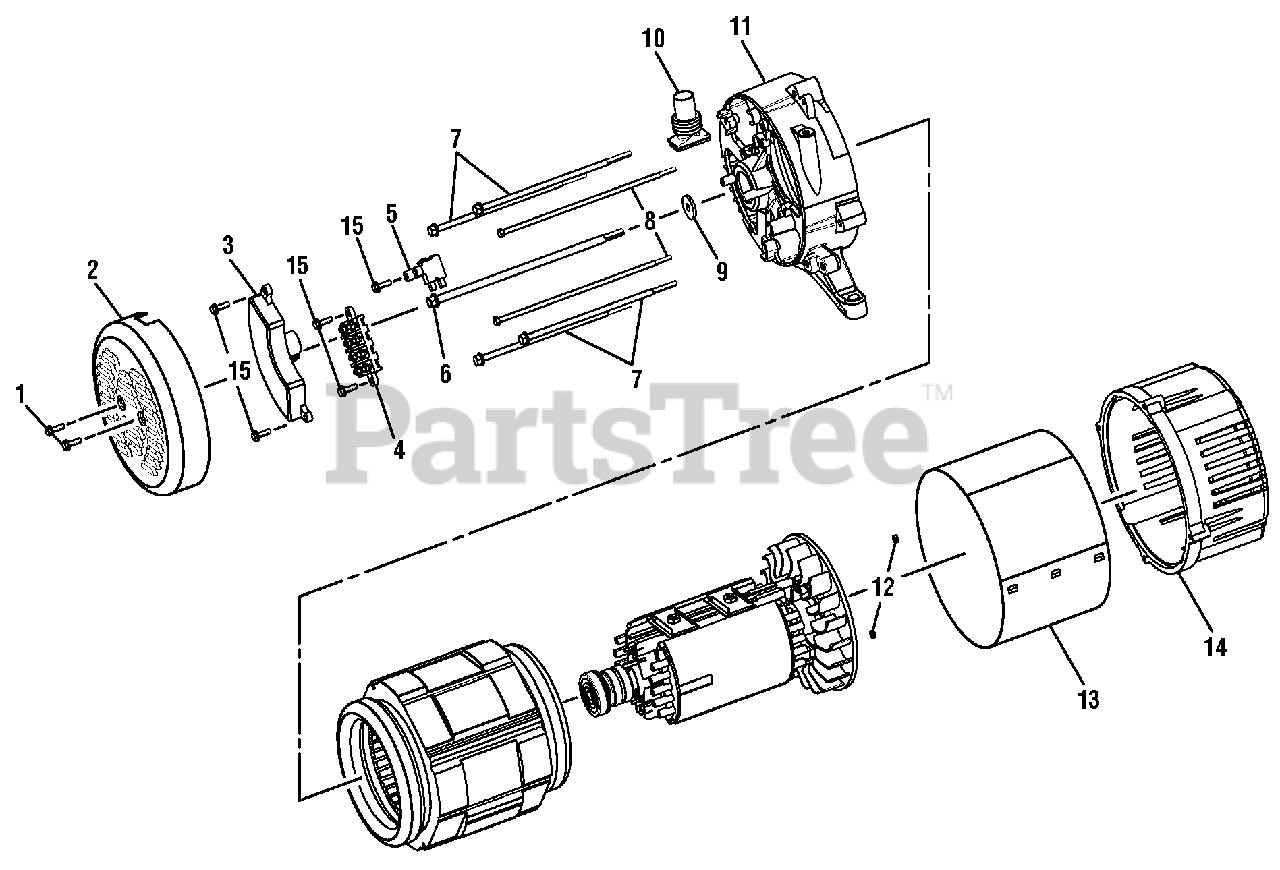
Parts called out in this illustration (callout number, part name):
1	Bolt (M5 x 12 mm, Hex Hd.)
2	Brush Cover
3	Automatic Voltage Regulator
4	Terminal Block
5	Brush Assembly
6	Bolt (5/16-24 x 235 mm, Hex Washer Hd.)
7	Bolt (M6 x 188 mm, Hex Washer Hd.)
8	Bolt (M5 x 210 mm, Hex Washer Hd.)
9	Washer (8 x 26 x 3t)
10	Rubber Boot
11	Bearing Housing
12	Hex Nut (M5)
13	Generator Head Cover
14	Adaptor Housing
15	Bolt (M5 x 16 mm, Hex Hd.)
